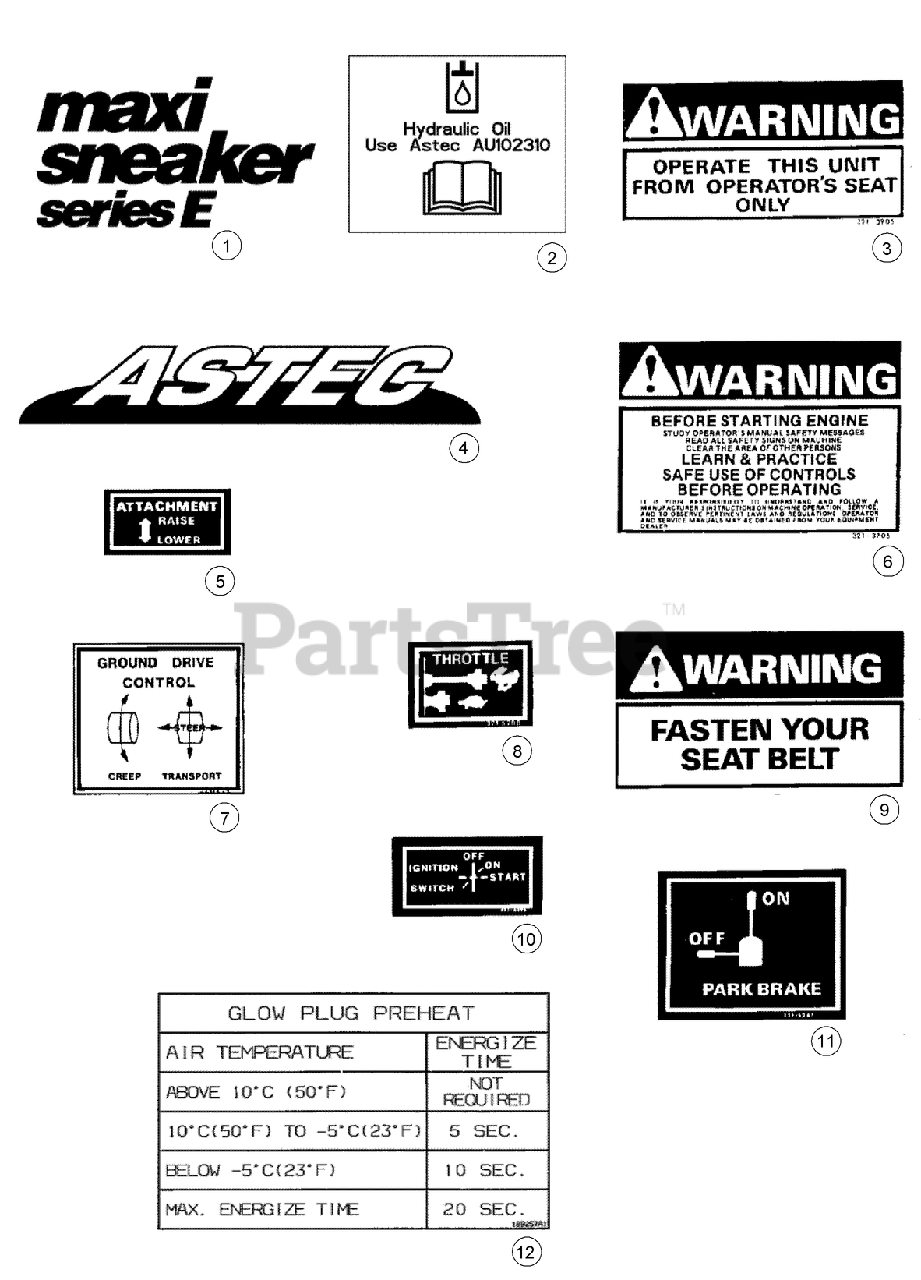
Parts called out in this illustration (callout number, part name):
1	DECAL - Maxi Sneaker Series E
2	DECAL - Hydraulic Fluid.
3	DECAL - Warning, Operate This Unit From Operator Seat Only
4	DECAL - Astec
5	DECAL - Attachment, Raise / Lower
6	DECAL - Warning, Before Starting Engine.
7	DECAL - Ground Drive Control, Creep/Transport
8	DECAL - Throttle
9	DECAL - Warning, Fasten Your Seat Belt
10	DECAL - Ignition Switch, Off / On / Start
11	DECAL - Park Brake, On / Off
12	DECAL - Glow Plug Preheat
